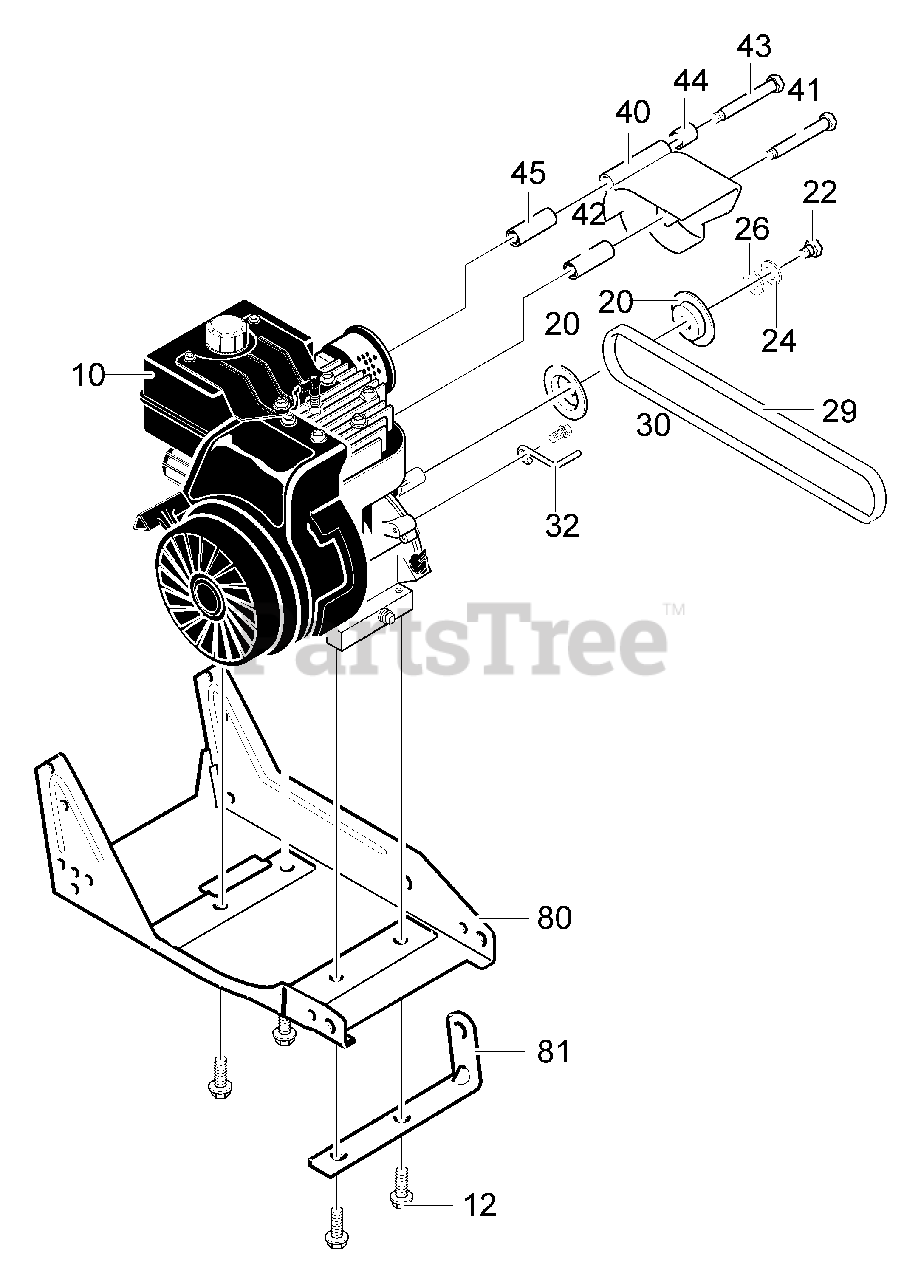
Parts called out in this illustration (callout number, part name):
10	Engine
12	Screw, 3/8-16x1.00
20	Pulley, Half
22	Screw, 5/16-24x1.00
26	Flatwasher
29	Belt, V4L 32.60LG
30	Screw and Washer Assy
32	Guide, Belt
40	Cover, Engine Pulley
41	Screw, 5/16-24x3.00
42	Spacer, Sleeve
43	Screw, 5/16-24x3.75
45	Spacer, Sleeve
80	Frame, Assy. Edger
